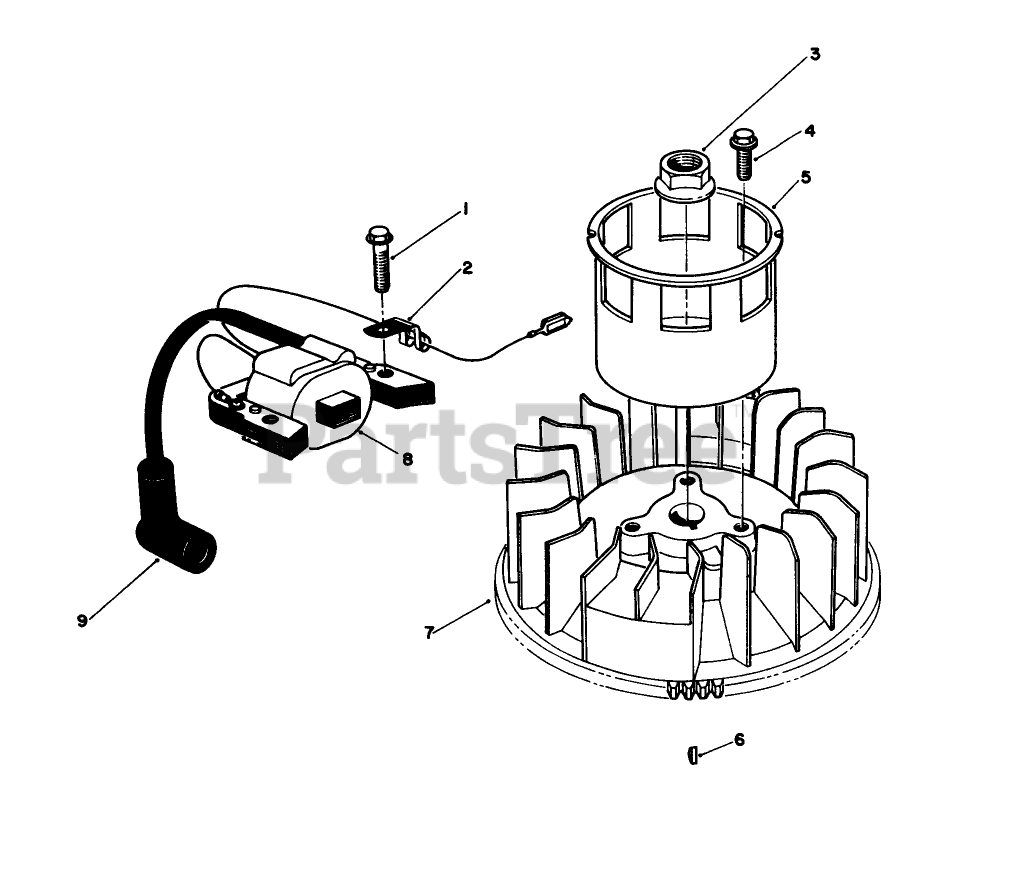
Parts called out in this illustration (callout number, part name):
2	CLAMP
7	FLYWHEEL
8	COIL
9	COVER
